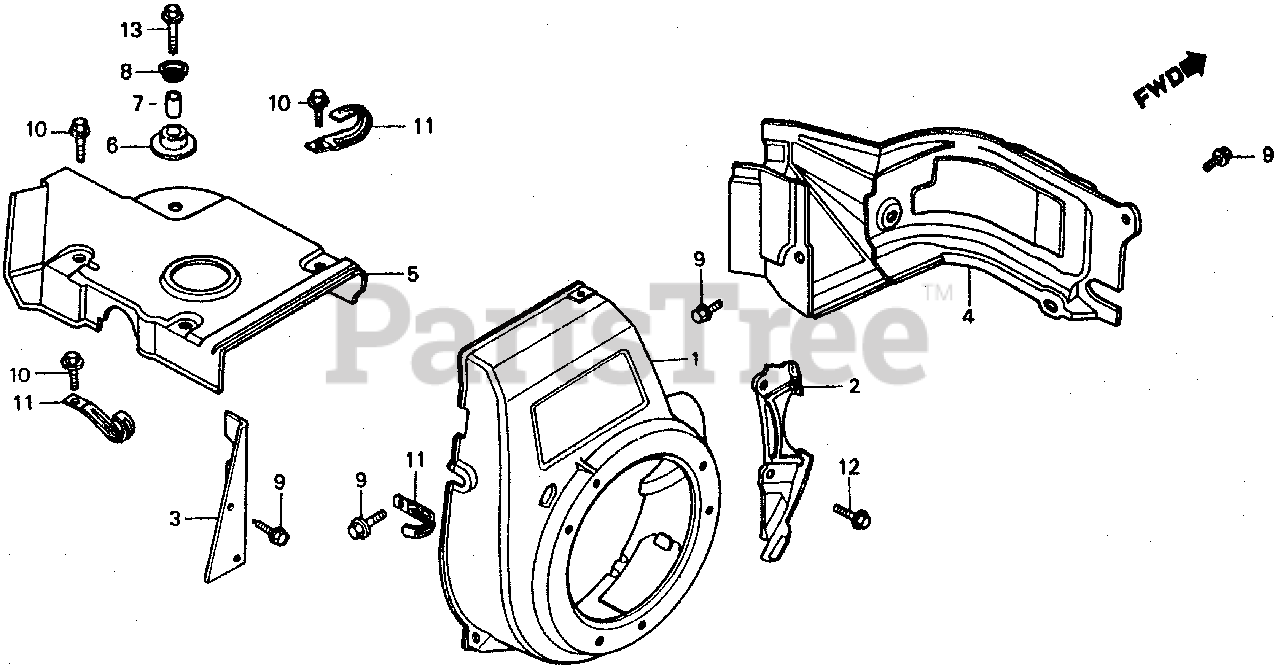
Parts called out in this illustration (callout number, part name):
1	COVER, FAN *R8* (BRIGHT RED)
2	PLATE, SIDE
3	GUIDE, AIR
4	SHROUD *R8* (BRIGHT RED)
5	COVER, TOP *R8* (BRIGHT RED)
6	RUBBER, STOPPER
7	COLLAR, DISTANCE
8	PLATE, STOPPER
9	BOLT, FLANGE (6X12) (CT200)
10	BOLT, FLANGE (6X14)
11	CLIP (2X50)
12	BOLT, FLANGE (8X20)
13	BOLT, FLANGE (8X50)
